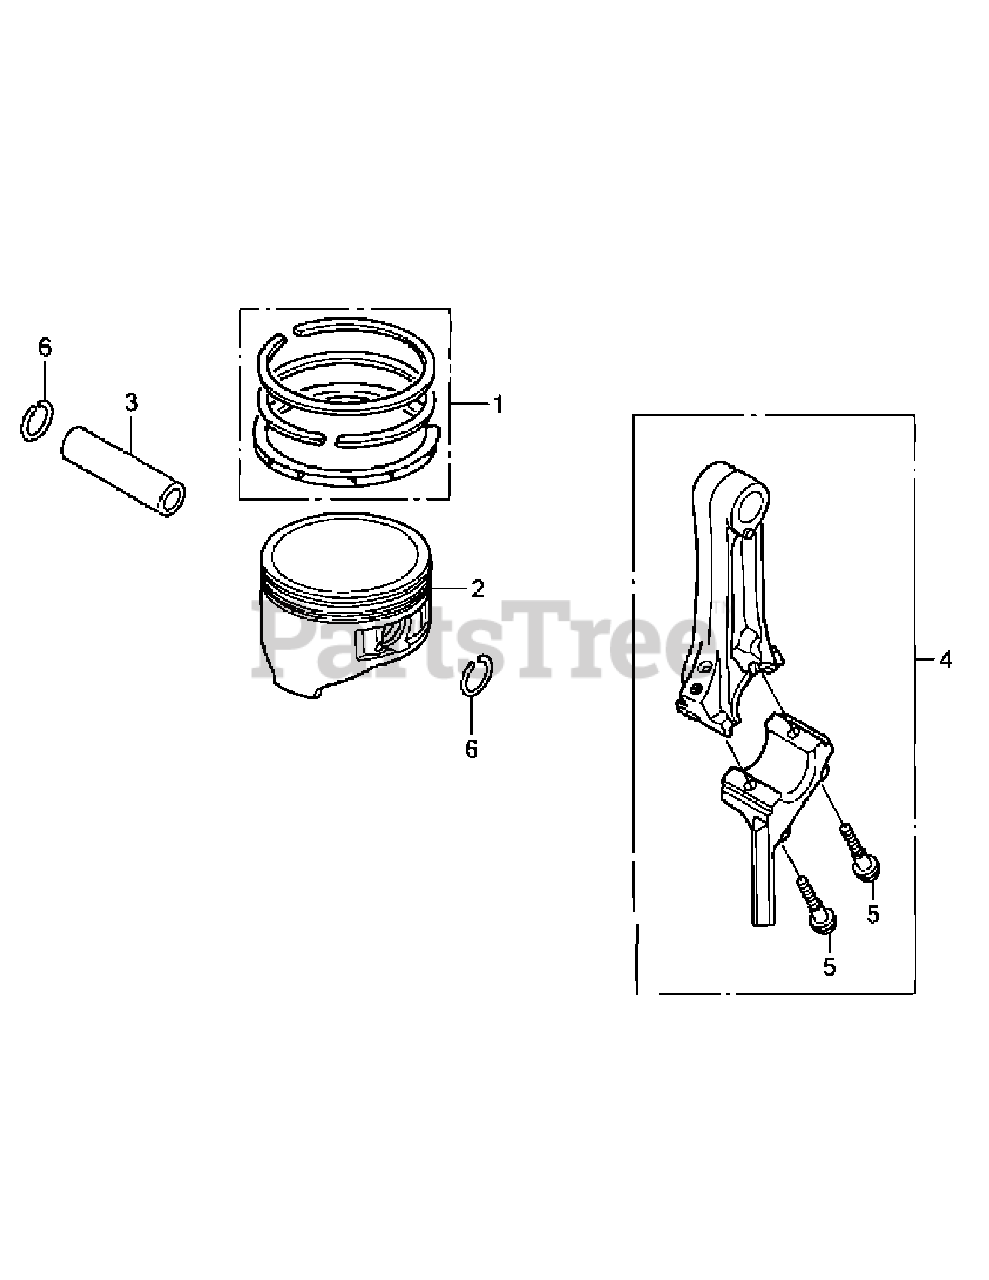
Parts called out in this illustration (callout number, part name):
1	Ring Set, Piston (Std.) (Teikoku)
2	Piston
3	Pin, Piston
4	Rod Assy., Connecting
5	Bolt, Connecting Rod
6	Clip, Piston Pin, 13Mm
